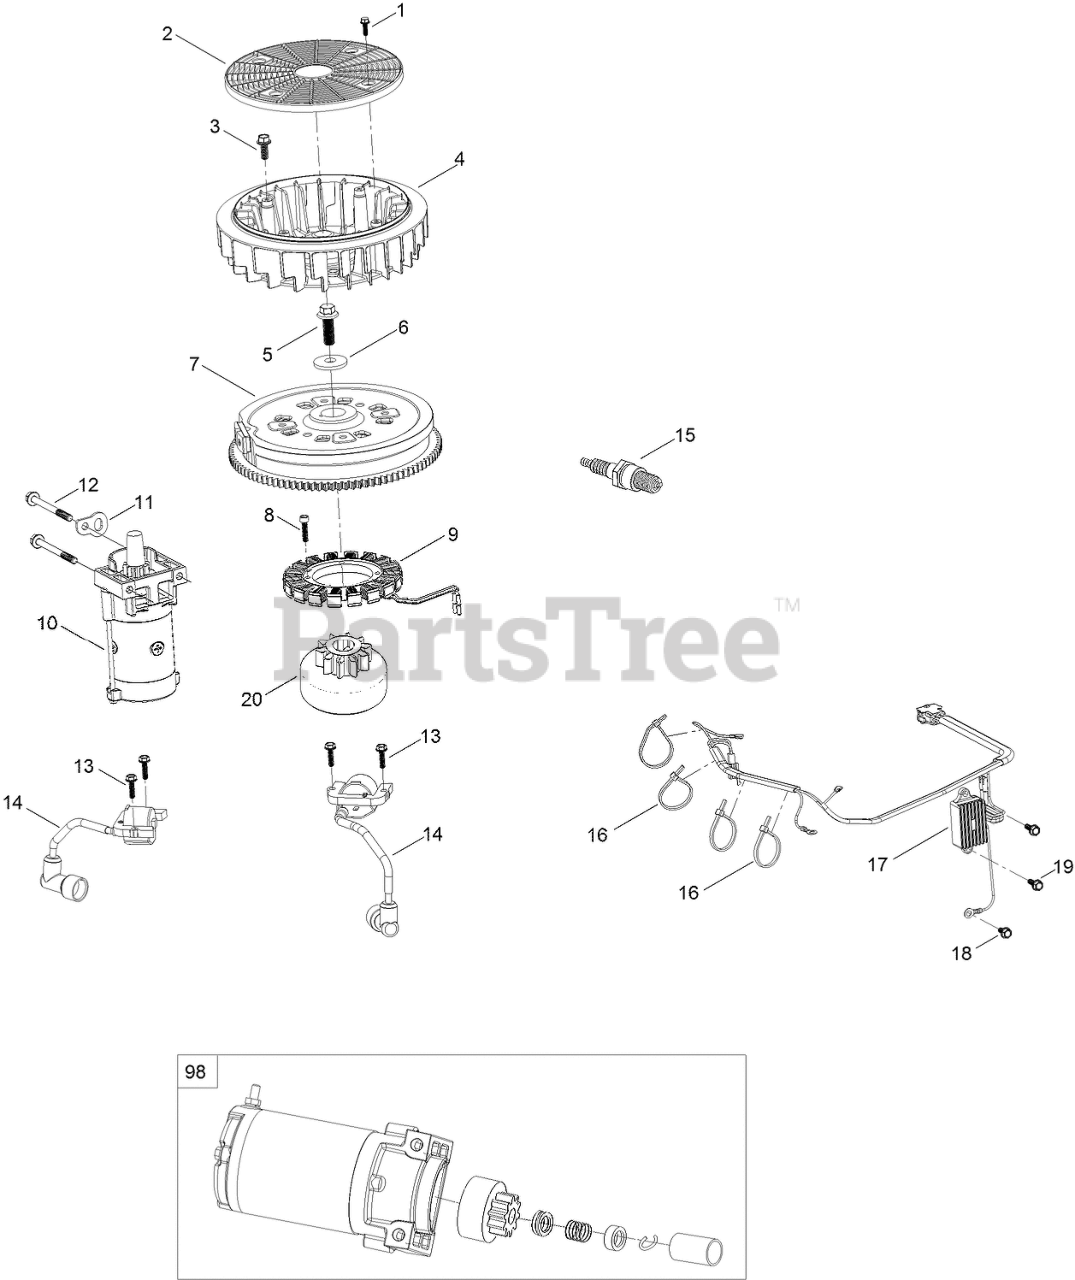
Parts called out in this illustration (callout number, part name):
1	SCREW-HWH
2	SCREEN-ROTATING
3	SCREW-HWH
4	FAN-COOLING
5	SCREW-HWH
6	WASHER-FLAT
7	FLYWHEEL
8	SCREW-HSH
9	ALTERNATOR
10	Motor-Starter
11	BRACKET-LIFT
12	SCREW-HHF
13	BOLT-FLANGE
14	IGNITION COIL ASM
15	SPARK PLUG
16	TIE-ZIP
17	REGULATOR-VOLTAGE W/HARNESS
18	SCREW-HHF
19	SCREW-HHF
20	PINION-STARTER
98	STARTER REPAIR KIT
